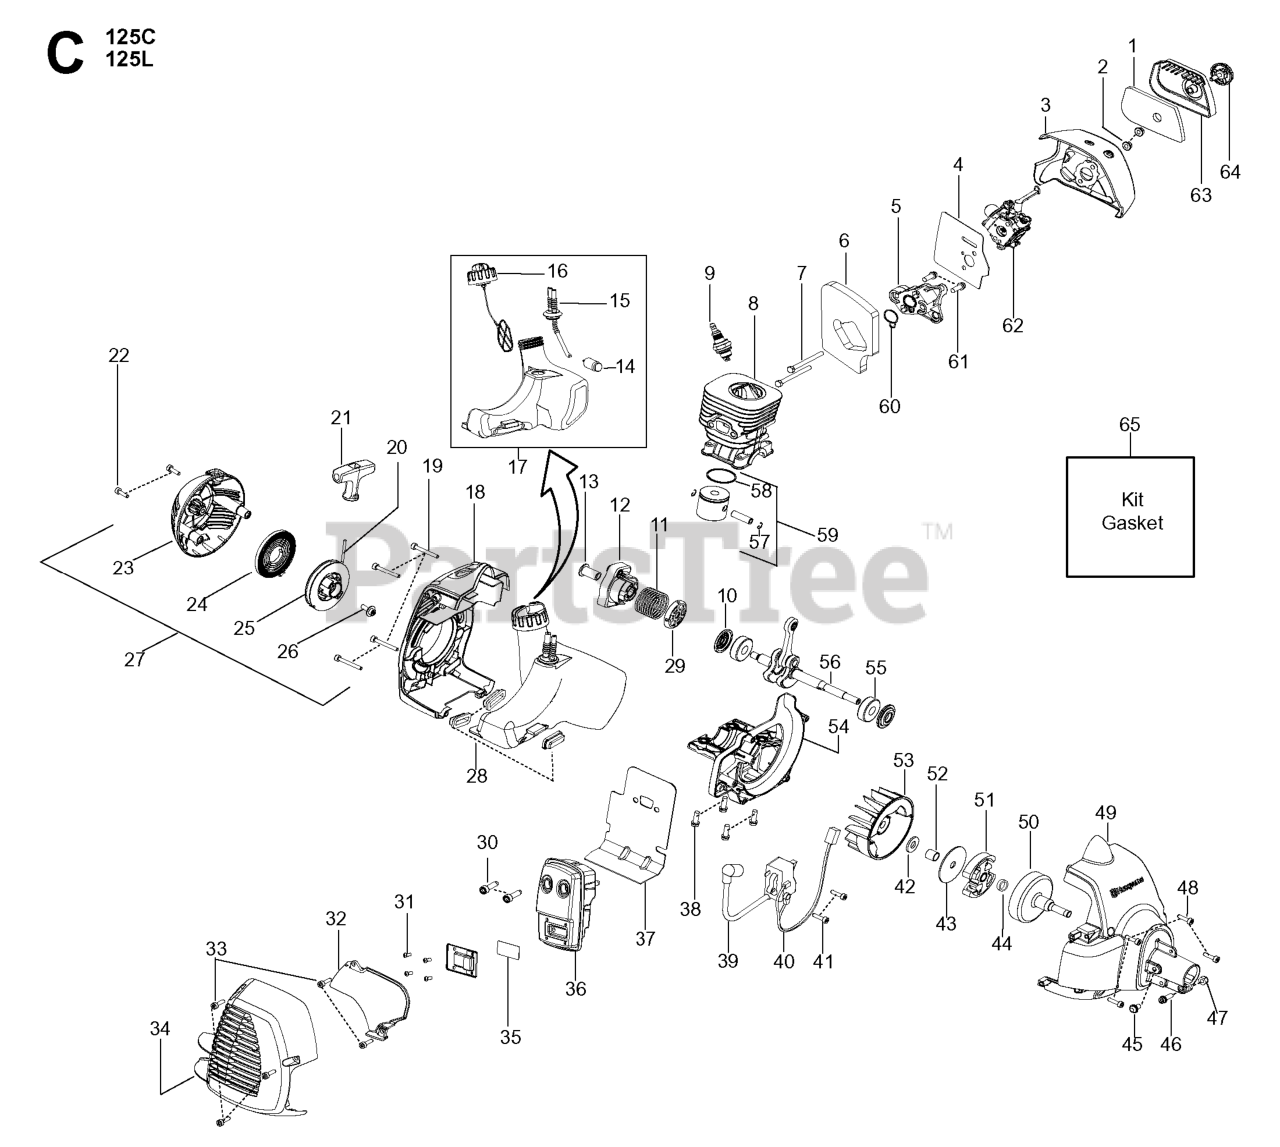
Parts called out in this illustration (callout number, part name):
1	FILTER AIRBOX
3	AIRBOX
4	KIT GASKET 28CC TRIMMER
5	CARB ADAPTOR
7	BOLT CARB ADAPTOR
8	CYLINDER
9	SPARK PLUG RCJ6Y NLA
10	KIT SEAL CRANKSHAFT
11	SPRING STARTER CUP
12	ASSY STARTER CUP
13	COUPLING STARTER
14	FUEL PICK-UP ASSY
15	KIT FUEL LINE
16	ASSY-CAP W/RETAINER
17	ASSY FUEL TANK
18	REAR SHROUD
21	STARTER HANDLE GRAY
23	HSG STARTER W/EYELET
24	%KIT STARTER SPRING
25	KIT STARTER PULLEY
27	STARTER HSG ASSY
28	ISOLATOR FUEL TANK
29	WASHER STARTER
30	BOLT MUFFLER
31	SCREW-10-16 X 1/2 HI-LO
32	SHIELD HEAT
33	SCREW M4 X 1.75 PT 16MM
34	MUFFLER GUARD
35	KIT SPARK ARRESTOR SCREEN
36	ASSY MUFFLER
37	KIT GASKET 28CC TRIMMER
38	SCREW-M5-0.8 X 25MM(TAP)
39	IGNITION MODULE MB45
40	ASSY MODULE LEAD WIRE
41	SCREW M4 X .70 TT 16MM
43	WASHER-CLUTCH
44	SPACER-CLUTCH
47	NUT HEX LOCK 10-24
48	SCREW M4 X .70 TT 16MM
49	FAN HSG ASSY
50	ASSY-CLUTCH DRUM
51	ASSEMBLY CLUTCH
52	SPACER FLYWHEEL
54	CRANKCASE CAST 28CC
55	BEARING RADIAL BALL (6201)
56	KIT CRANKSHAFT ASSY
57	WRIST PIN RET.
58	RING PISTON
59	KIT PISTON 28CC TRIMMER
60	KIT GASKET 28CC TRIMMER
61	SCREW-M5-0.8 X 25MM(TAP)
62	KIT CARBURETOR
63	COVER-AIR BOX
64	KNOB ASSY AIRBOX COVER
65	KIT GASKET 28CC TRIMMER
